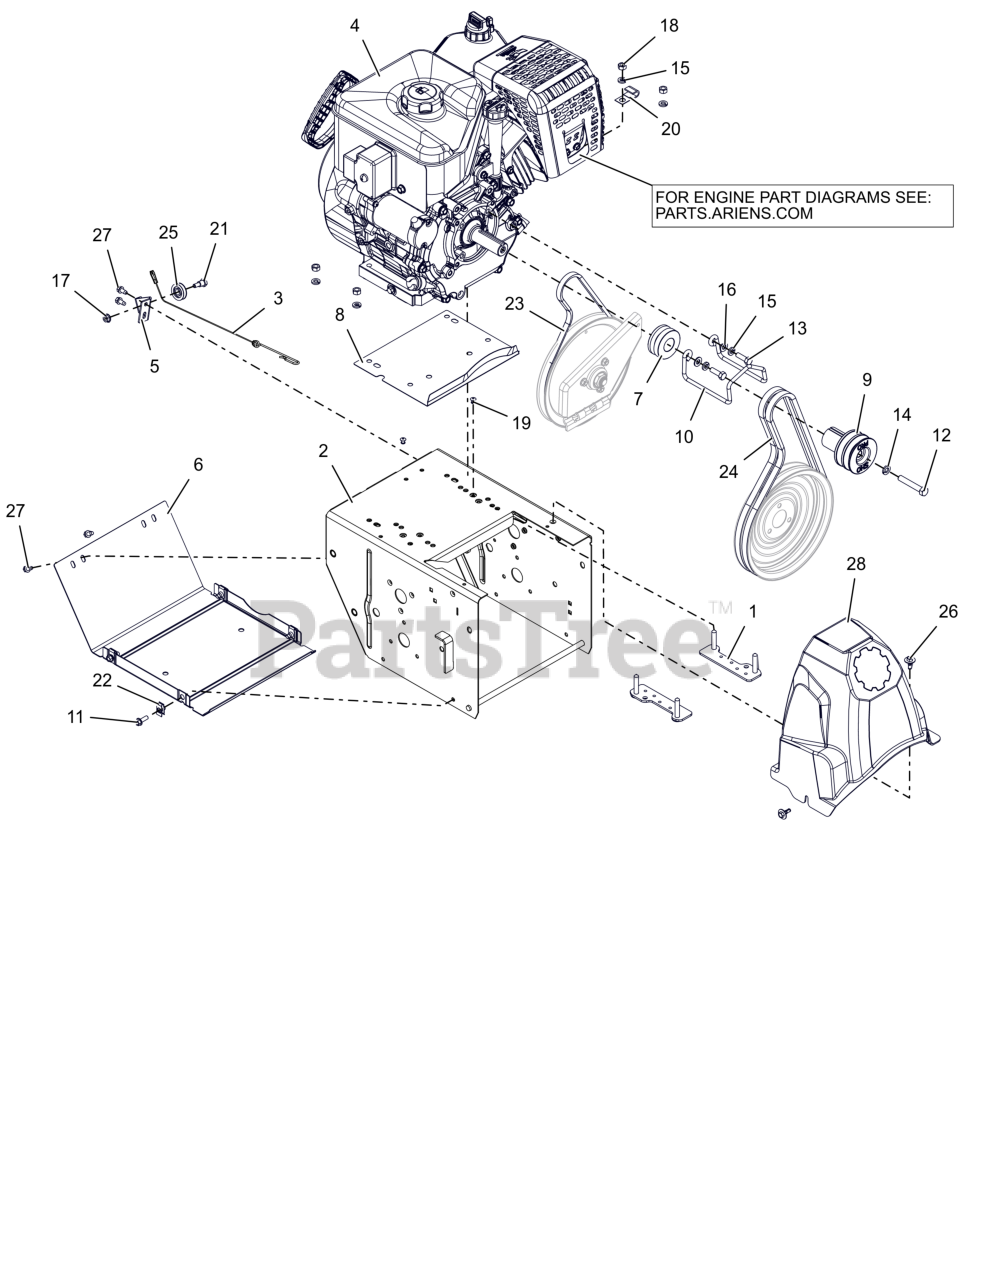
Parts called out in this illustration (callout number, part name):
1	STRAP, BOLT-LARGE
2	FRAME, MAIN - 14GA DELUXE (ORANGE)
3	CABLE, LOWER TRACTION,SS & PRO
4	ENGINE, AX420 GEN 3 120V/60W
5	BRKT, CABLE PULLEY
6	COVER, BOTTOM
7	SHEAVE, TRACTION (KEYLESS)
8	BAFFLE, WATER - LARGE BLOCK (ORANGE)
9	SHEAVE,ATTACHMENT-SHO 2 GRV
10	FINGER, BELT
11	BLT, HWH .25-20X.75 G5 ZCC
12	BLT, HEX .38-24X2.25 G5 ZCC
13	BLT, HEX 0.3125-24X1 G5 ZCC
14	WSHR,LK-REG .375X.094 ZCC
15	WSHR, LK-HVY .312X.097 ZCC
16	WSHR,FLT .344X.688X.065 ZCC
17	NUT-LK-TOP-FLG .250-20 GF ZCC
18	NUT, HEX .312-18 ZCC
19	RVT, POP .1875 ZCC
20	J-CLAMP
21	BOLT, SHLDR -.375 X .375 X .25-20
22	NUT-RTNR .25-20X.56
23	V-BELT, 3L-WRAPPED
24	V-BELT, HA-RAW EDGE (SET)
25	PULLEY, CABLE
26	SCR-TAP .25-20X.5 CAPTIVE
27	SCR-TAP .25-20X.50 HWH ZCC
28	COVER, BELT
